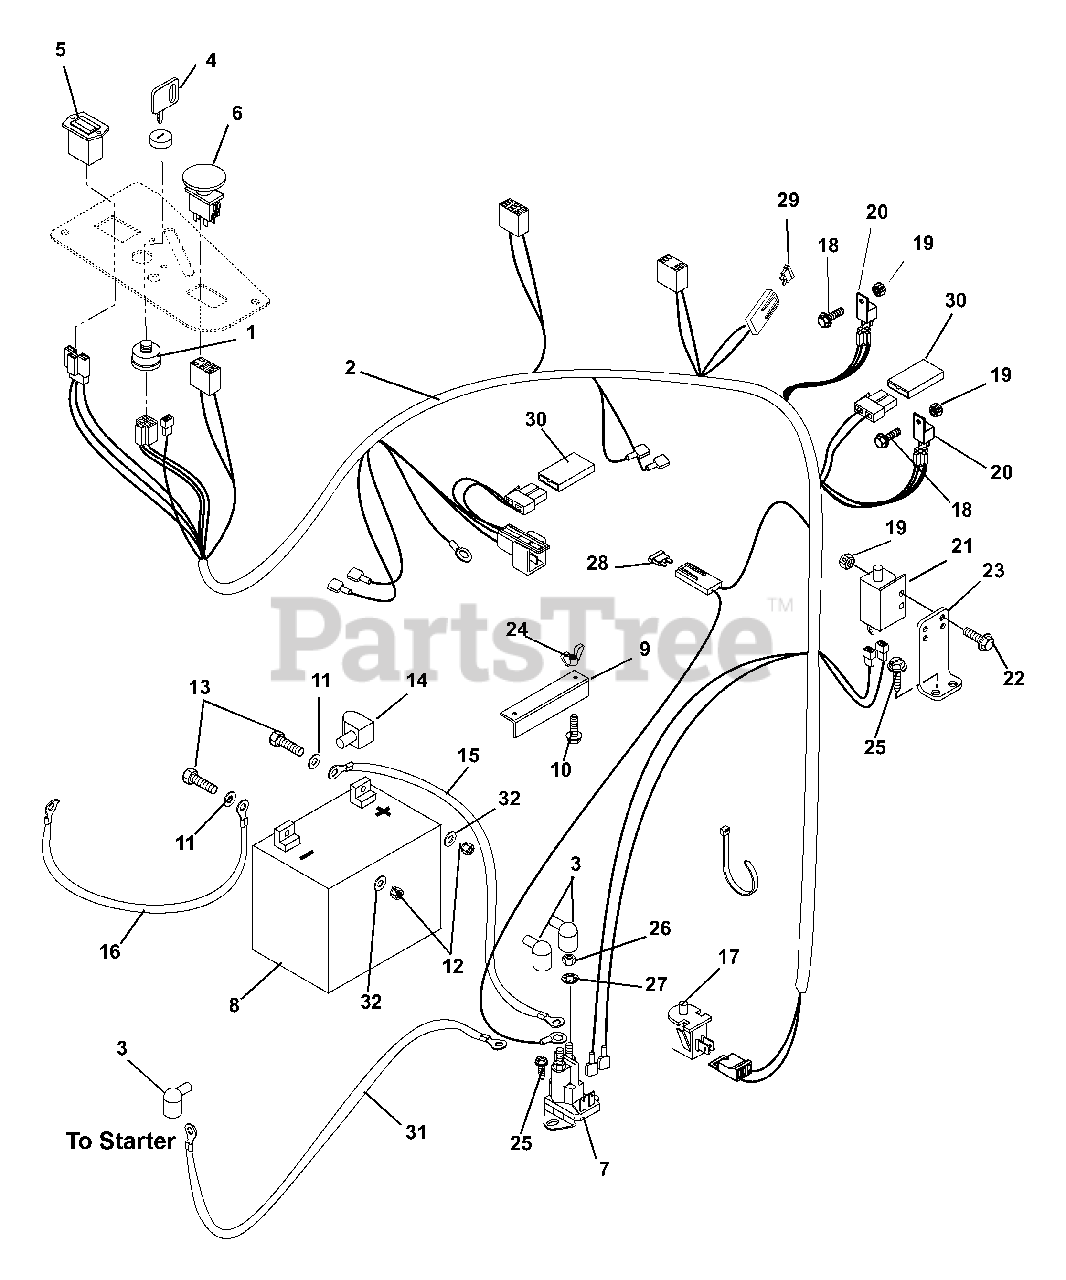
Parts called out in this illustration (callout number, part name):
1	SWITCH, IGNITION
2	HARNESS,CZ-EYEQ REMOTE SOL.
3	BOOT, EYELET TERMINAL
4	KEY, W/ SHIELD
5	HOURMETER-QUARTZ 80VDCMAX
6	SWITCH, CLUTCH
7	SOLENOID
8	BATTERY, 300 CCA 10U1L
9	HOLD DOWN
10	BLT-RDHDSQNK .25-20X7.50 GR2YZ
11	@WSHR-FL-STL.281X.62X.065 YWZC
12	@NUT-HEX .25-20 YWZC
13	@BLT-HEX .25-20X.75 GR5 YWZC
14	INSULATOR
15	CABLE, POS. BAT. 9.00"
16	CABLE, NEGATIVE BATTERY 24.00
17	SWITCH- SNAP MTG N.O.
18	@SCR-MCH 10-24X.50 HWH YWZC
19	@NUT-LK-NYL 10-24 W/INSRT YWZC
20	RELAY
21	SWITCH- SINGLE POLE N.O.
22	@SCR-MCH 10-24X.75 HWH YWZC
23	BRAKE SWITCH MOUNT - BLACK
24	NUT-LK WING .250-20 YWZC
25	@SCR-TAP .25-20X.50 HWH TR YWZ
26	NUT-JAM .31-24 YWZC
27	@WSHR-LK .31X.078 REG YWZC
28	FUSE-25 AMP ATC TYPE
29	FUSE 20AMP
30	DIODE, CONNECTOR SHELL
31	CABLE, STARTER .31X23.00X.31
32	@WSHR-LK .25X.062 REG YWZC
